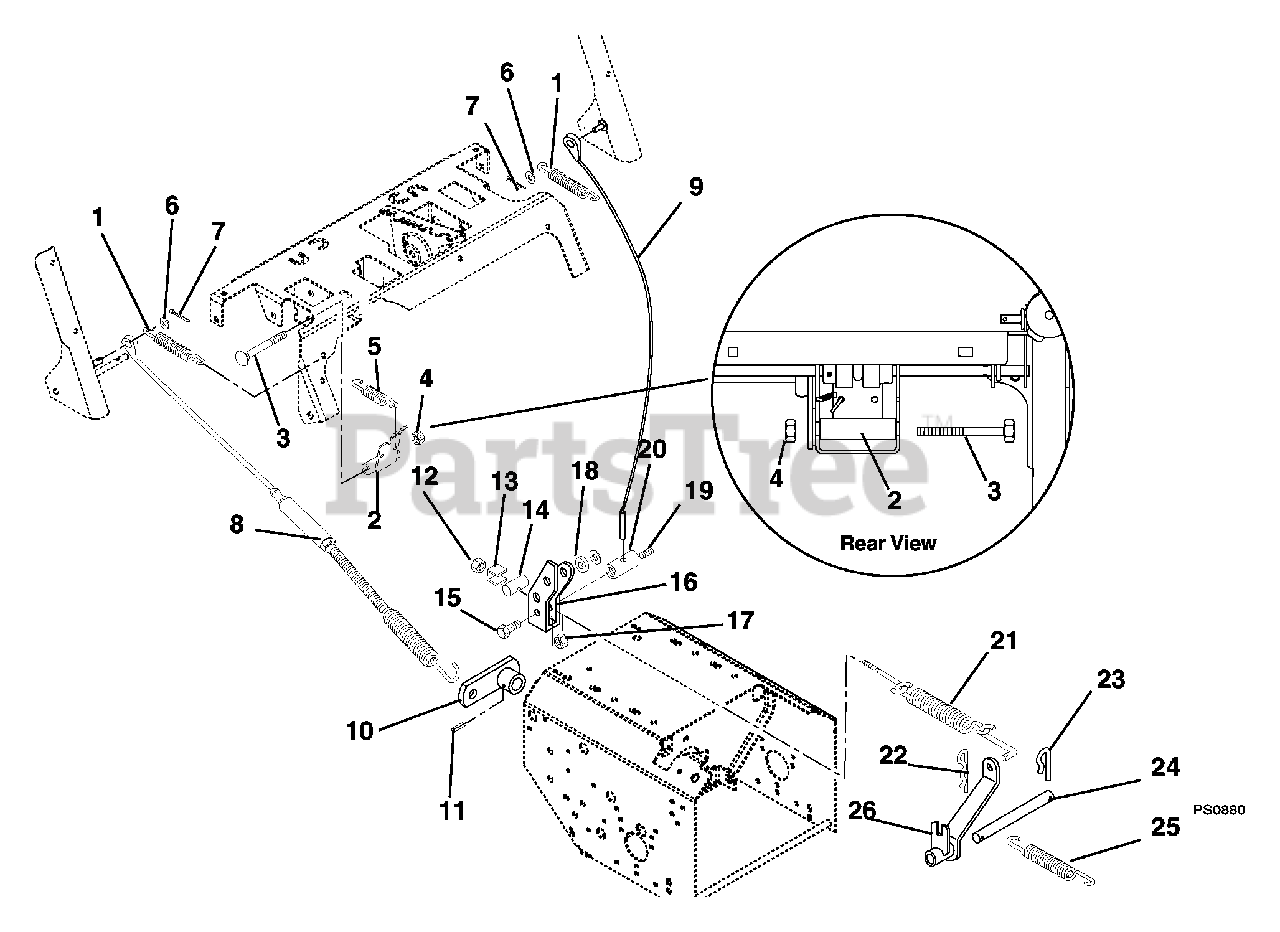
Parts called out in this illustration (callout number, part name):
1	Spring, Tension .056 x .50 x 3.76
2	Arm, Interlock
3	Bolt, Hex .38-16X3.00 Grade 5
4	Nut, Locking Center .38-16
5	Spring, Tension .05 x .44 x 38 x 1.45
6	Washer, Flat Steel .28 x .62 x .065
7	Pin, Cotter .09 x .50
8	Cable, Auger
9	Cable, Traction
10	Lever, Clutch
11	Pin, Roll .16 x .88
12	Nut, Locking Nylon .31-18
13	Spacer, Adapter
15	Bolt, Hex .31-18 x .75 Grade 5
16	Yoke, Clutch Engagement
17	Nut, Locking Center .31-18
18	Spacer 1.00 x .64 x .38
19	Screw, Set .31-18 x .38 Socket Head
20	Rod Adapter
21	Spring Assembly
22	Pin, Hair Internal .06 x .18 x .77
23	Clip, Spring
24	Rod, Fork Pivot
25	Spring, Tension .08 x .73 x 3.06 Weldment
26	Clutch Fork
